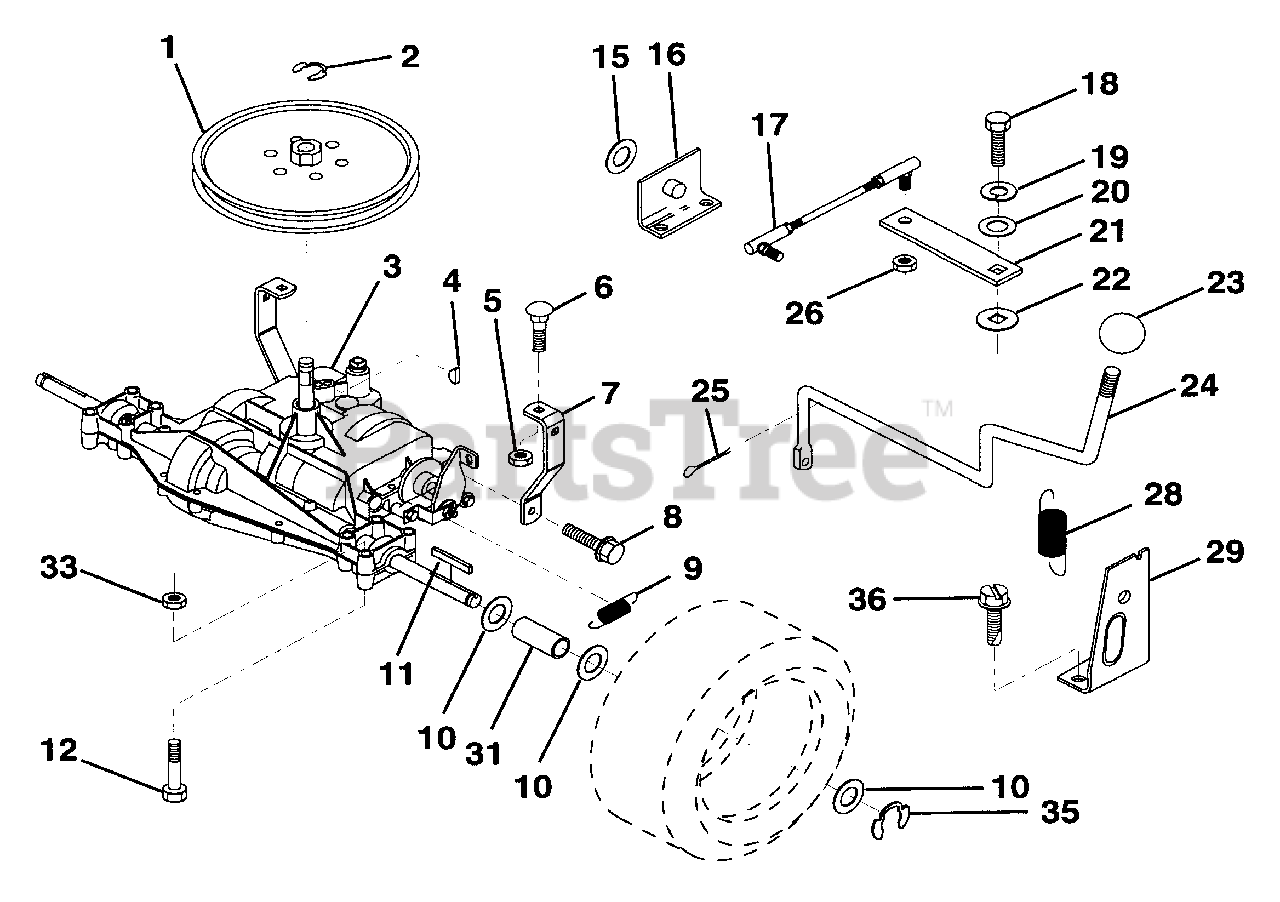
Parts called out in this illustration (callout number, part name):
2	Ring, Retainer
3	Transaxle, Dana Model No. 4360-79
4	Key, Woodruff #9
5	Nut, Crownlock 5/16-18
6	Bolt, Carriage 5/16-18 UNC x 3/4
7	Strap, Torque
8	Screw 5/16-18 x 3/4
9	Spring, Brake
10	Washer 25/32 x 1-1/4 x 16 Gauge
11	Key, Square
12	Bolt, Hex, Fin. 3/8-16 Unc x 2-3/4
15	Washer 17/32 x 1 x 16 Gauge
16	Support Handle Shift, LH
17	Link, Shift
18	Bolt, Hex, Fin. 1/4-28 UNF x 3/4 Grade 8
19	Washer, Lock 1/4
20	Washer 9/32 x 3/4 x 10 Gauge
21	Arm, Shift
22	Washer, Shift Plate
23	Knob, Duckhead
24	Rod Assembly, Shift
25	Pin, Cotter 1/8 x 1
26	Locknut 5/16-24 UNF
28	Extension, Spring
29	Support Handle Shift, RH
31	Spacer Split
33	Nut Crownlock 3/8-16 Unc
36	Screw Thd. cut 1 /4-20 x 1 /2
